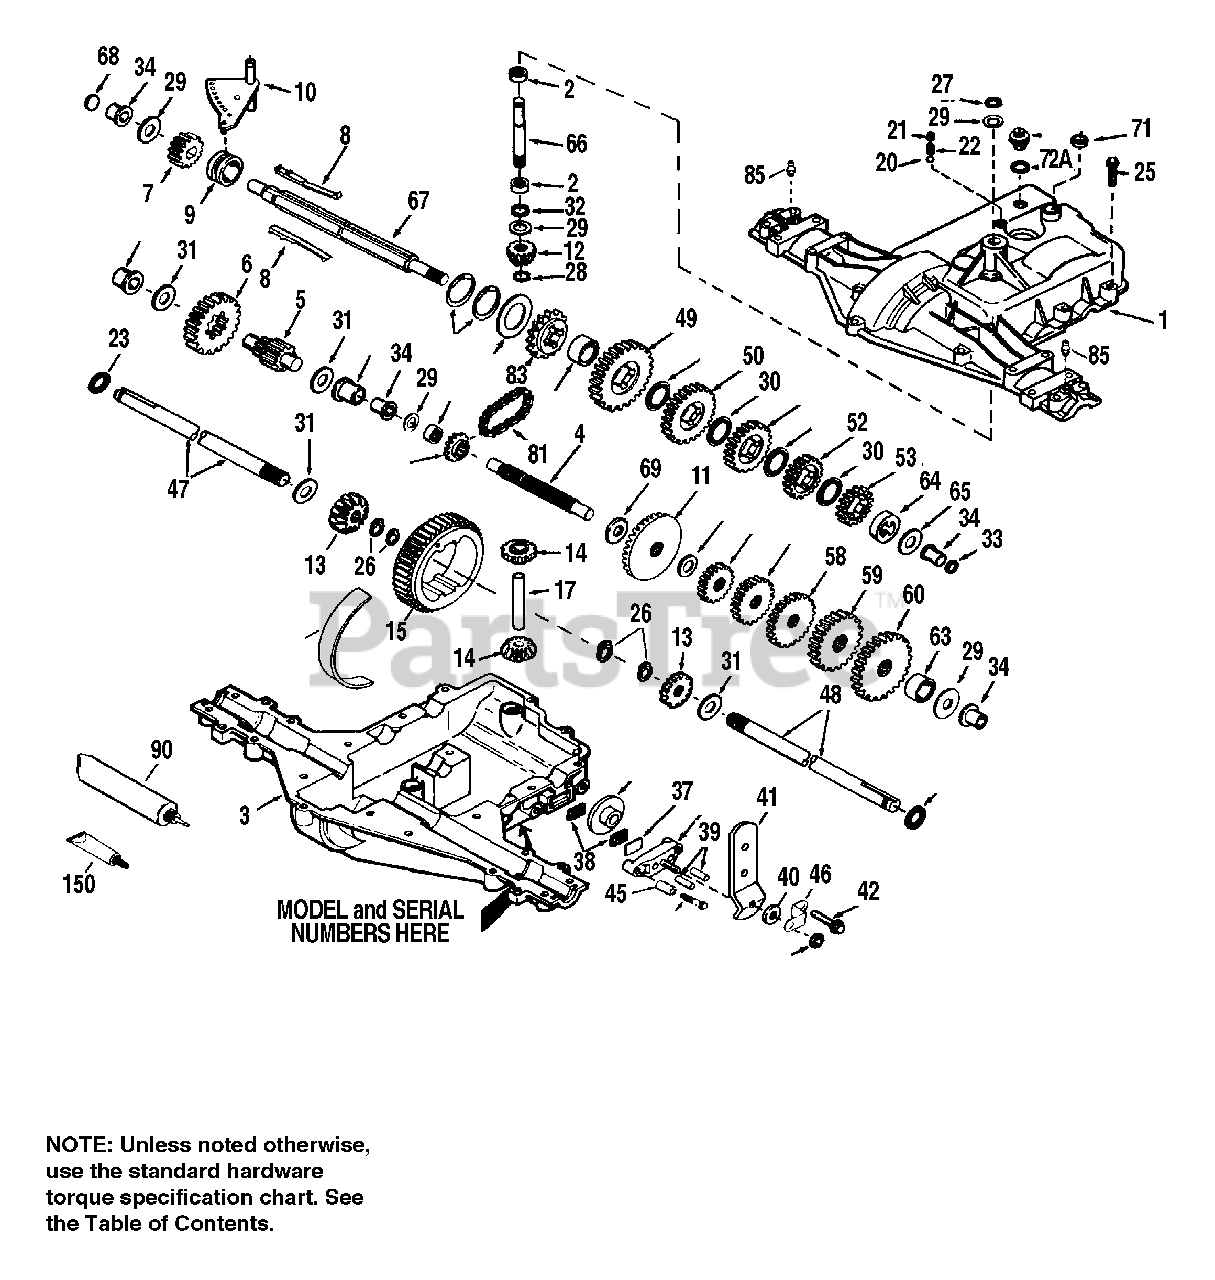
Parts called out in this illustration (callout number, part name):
1	Transaxle Cover
2	Needle Bearing
3	Transaxle Case
4	Countershaft
5	Output Shaft & Pinion
6	Output Gear (35 teeth)
7	Spur Gear (15 teeth)
8	Shift Key
9	Shift Collar
10	Shift Rod & Fork
11	Bevel Gear (42 teeth)
12	Input Bevel Pinion
13	Bevel Gear (16 teeth)
14	Differential Pinion
15	Ring Gear
16	Bearing Strip
17	Drive Pin
20	Steel Ball, 5/16" dia.
21	Set Screw, 3/8-16 x 3/8"
23	Seal Ring
25	Screw, 1/4-20 x 1-1/4"
26	Retaining Ring (pkg. of 2)
27	Retaining Ring
28	Retaining Ring
33	Square Cut Ring
34	Flanged Bushing
35	Flanged Bushing
36	Brake Disk
37	Brake Pad Plate
38	Brake Pad (pkg of 2)
39	Dowel Pin
41	Brake Lever
42	Screw, 1/4-20 x 1-1/4"
42A	Screw, 1/4-20 x 2-1/4"
43	Locknut, 5/16-24
44	Brake Pad Holder
46	Brake Lever Bracket
47	Axle (11-5/32" long)
48	Axle (16-13/16" long)
49	Spur Gear (37 teeth)
50	Spur Gear (30 teeth)
51	Spur Gear (25 teeth)
52	Spur Gear (22 teeth)
53	Spur Gear (19 teeth)
56	Spur Gear (12 teeth)
57	Spur Gear (20 teeth)
58	Spur Gear (25 teeth)
59	Spur Gear (28 teeth)
60	Spur Gear (31 teeth)
63	Countershaft Spacer
64	Output Shaft Spacer
66	Input Shaft
67	Shifter & Brake Shaft
71	Square Cut Ring
72	Threaded Plug, 9/16-18
77	Inverted Retaining Ring (pkg. of 2)
81	Roller Chain (No. 41 chain, 22 links)
82	Sprocket (10 teeth)
83	Reverse Sprocket (14 teeth)
85	Lubrication Fitting
90	Grease (32 oz. btl. Bentonite grease)
150	Gasket Eliminator (Loctite #515)
